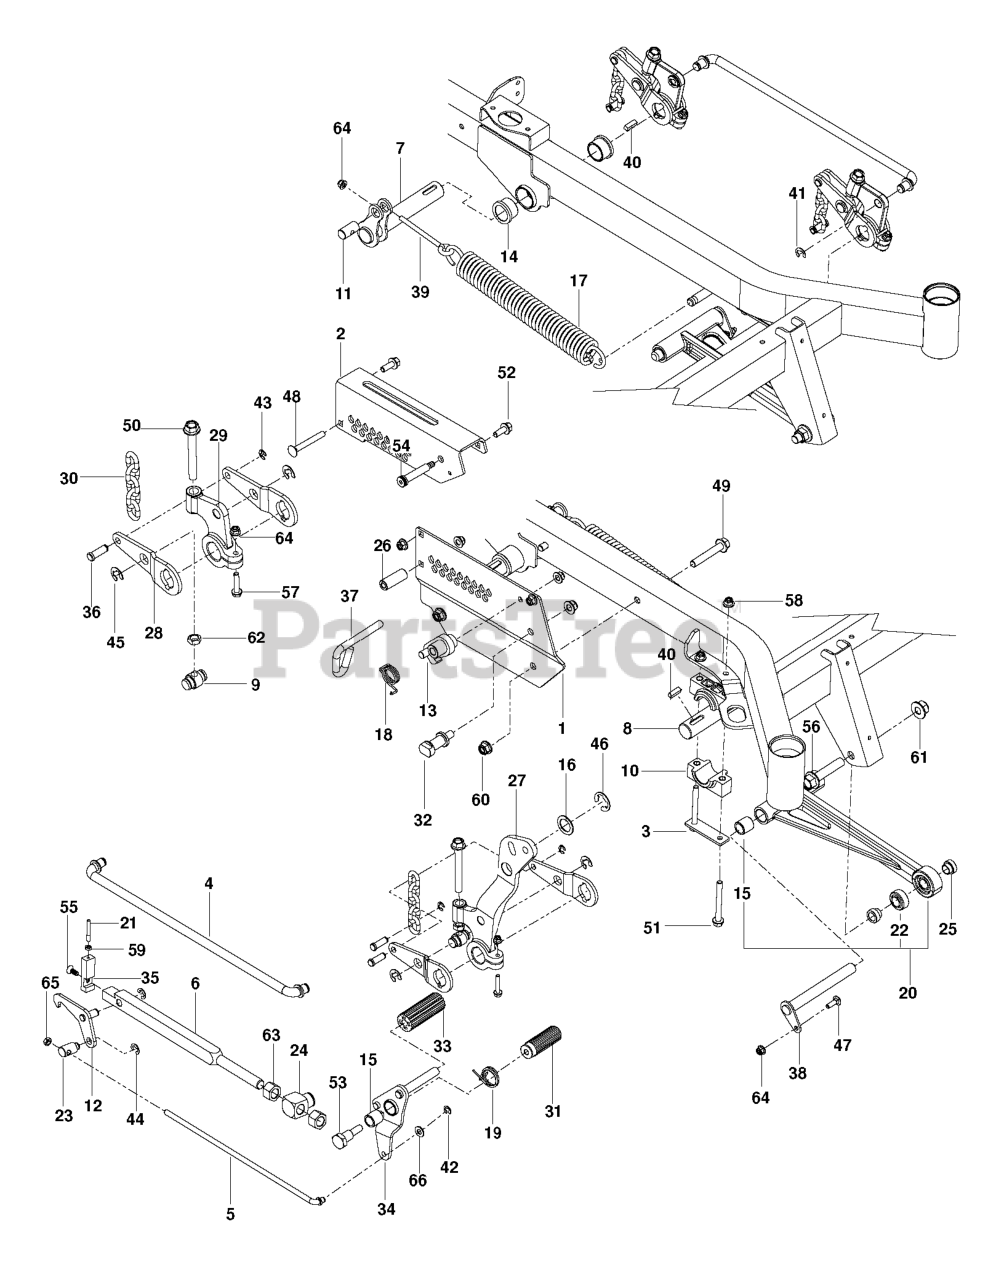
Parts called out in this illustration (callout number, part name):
1	PLATE, INNER HEIGHT, ORANGE
2	PLATE, OUTER HEIGHT ORG
3	PLATE, PILLOW BLACK
5	ROD, HEIGHT LATCH
6	BAR, HEIGHT
7	SHAFT, RR LIFT
8	SHAFT, LIFT, FT
9	SHAFT, LIFT TRUNION WSL
10	BLOCK, PILLOW
11	PIVOT, SPRING
12	LATCH, HEIGHT WLDMT
13	LATCH, TRANSPORT WLDMT
14	BUSHING, FLANGE 1.25 X 1.0
15	BUSHING, SLEEVE 3/4 X 1.0
16	MACHINE BUSHING
17	SPRING, EXTENSION
18	SPRING, TORSION
19	SPRING, TORSION
20	ASSEMBLY, STRUT
21	LINK, INDICATOR
22	BALL JOINT, 3/4" SWIVEL
23	SWIVEL, HEIGHT LATCH
24	SWIVEL, HEIGHT BAR
25	SPACER, STRUT
26	SPACER, HEIGHT PLATE
27	ARM, LIFT LEVER
28	ARM LIFT BLK
29	ARM, CAST LIFT
30	LIFT CHAIN
31	PEDAL, DECK HEIGHT
32	GUIDE, HEIGHT BAR
33	PAD, FOOT PEDAL
34	PEDAL, RELEASE WLDMT
35	CAP, HEIGHT BAR
36	PIN, 7/16 CLEVIS
37	PIN, HEIGHT
38	PIN, STRUT
39	EYE BOLT 4.5`
40	KEY, 5/16 SQ X 1.0
41	E-RING 5/8
42	E RING 3/8"
43	RING, E, 7/16
44	E-RING 1/2 (2 2)
45	E RING 3/4
46	E-RING 1"
47	RHSNB 5/16C X 1
48	3/8-16 X 3` CARR BOLT
49	HFFS 1/2-13 X 3 GD 5 ZD
50	HHFS 1/2-13 X 4 GR 5
51	HHFS 3/8-16 X 3.5 GD 5 ZD
52	HHFS 3/8-16 X 1 GRD 5 ZD
53	BOLT, SHOULDER
54	BOLT, SHOULDER, 1/2 X 2.25
55	SCREW, 5/16-18 X 3/4 FLAT HEX
56	HHFS 5/8-11 X 3.0 GD 8 ZD
57	HHFS 5/16-18 X 1.5 GD 5
58	NUT 3/8-16 HEX FLG NYLOC ZD
59	NUT 1/4-20 JAM
60	NUT, 1/2-13 HEX FLG NYLOC ZD
61	NUT 5/8-11 FLG NYLOC ZD
62	NUT 1/2 HEX JAM
63	NUT 3/4-10 HEX ZD
64	5/16-18 NYLOC FLANGE NUT
65	NUT 3/8-24 JAM
66	WASHER 3/8 SAE FLAT
